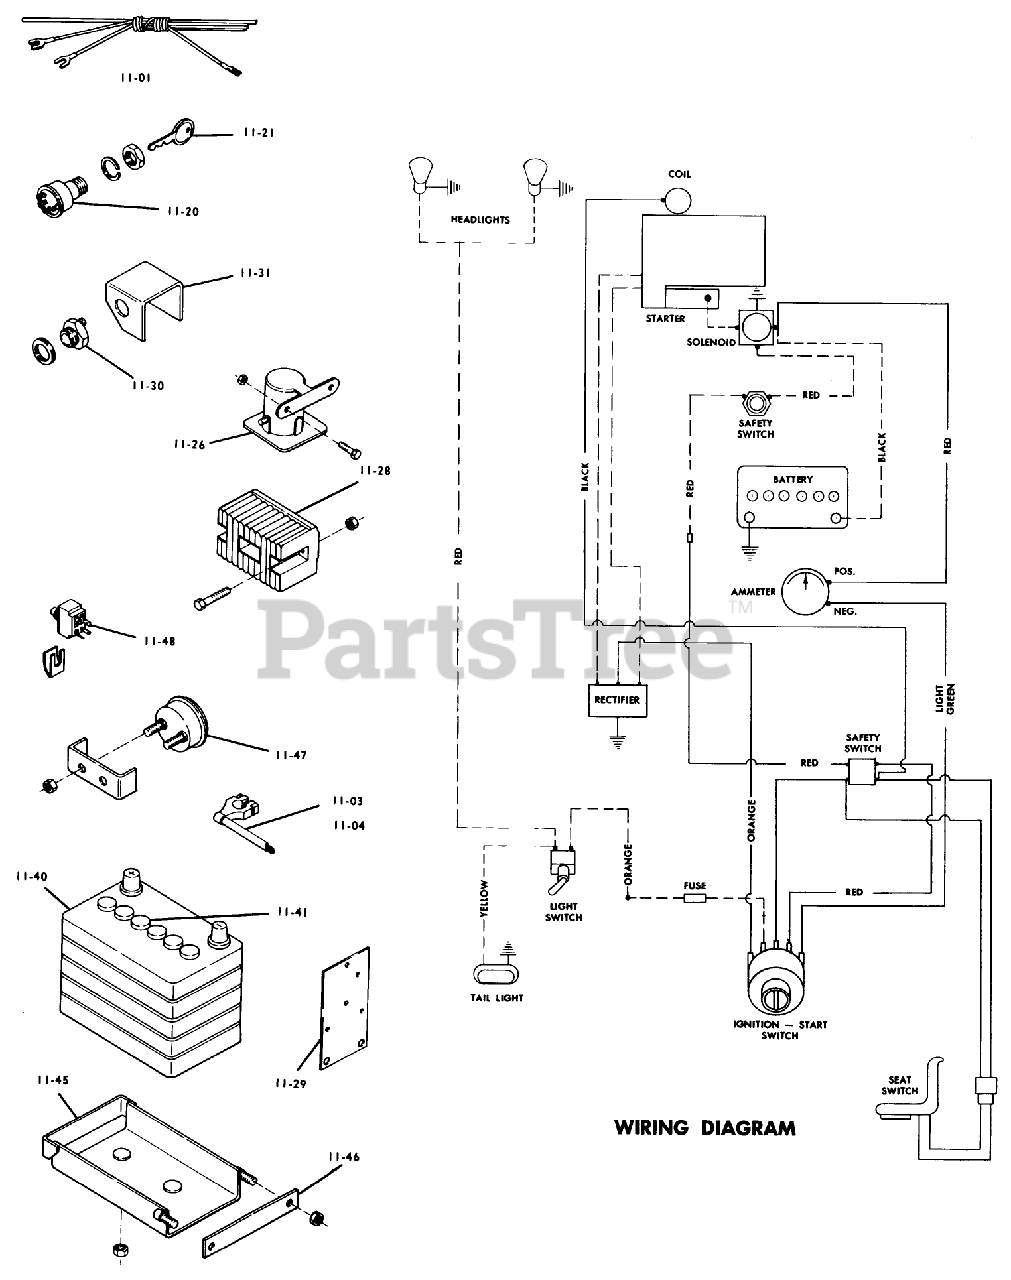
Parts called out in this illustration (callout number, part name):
11-01	WIRING HARNESS & DIA
11-02	Grommet
11-03	Wire
11-04	Wire
11-20	SWITCH-IGNITION
11-21	Key-EL
11-26	Solenoid
11-28	REGULATOR-RECTIFIER
11-29	PLATE COIL & SOL MTG
11-30	SWITCH SAFETY
11-31	Bracket
11-40	Battery
11-45	Battery Box
11-46	LINK BATTERY CLAM R
11-47	AMMETER W/CLAMP
11-48	SWITCH-CLUTCH
